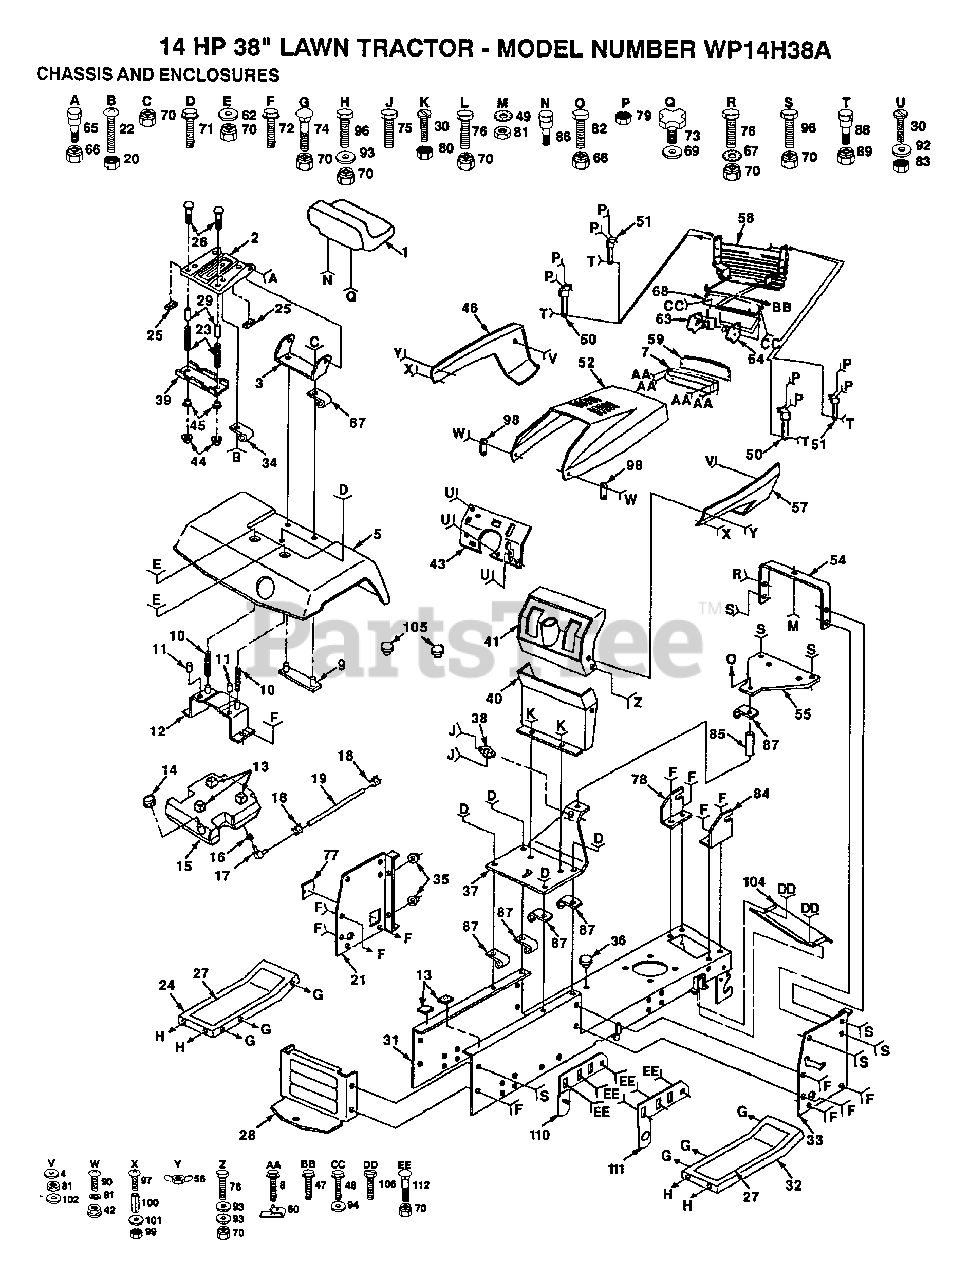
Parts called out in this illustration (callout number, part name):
4	WASHER PM
5	FENDER
10	SPRING COMPRESSIO
11	NUT-PUSH YT
13	PAD-SPACER LT
16	BUSHING OUTLET T
17	FUEL TANK STEM GT
18	HOSE CLAMP
20	"NUT,KEPS"
21	PANEL DASH LH
23	SPRING
25	STRIP FORM
27	FOOTREST PAD
28	DRAWBAR LT/YT
29	SPACER SPLIT
30	SCREW
33	DASH PANEL RH
39	BRKT SWITCH
40	LOWER DASH
42	WELDNUT
45	BUSHING
47	SCREW
48	SCREW
54	SUPPORT ASS'Y
57	"PANEL,SIDE RH "
59	LENS LT
60	"""J"" FASTENER LT"
62	WASHER
63	SUPPORT LH YTH
64	SUPPORT RH YTH
67	LOCKWASHER
69	WASHER
71	SCREW LT
72	SCREW
73	"KNOB 1/2"" YT"
74	BOLT
76	BOLT
77	COVER ACCESS
78	SUPPORT LH YTH
79	NUT
82	BOLT
84	SUPPORT RH YTH
85	SPACER
86	"BOLT,SHOULDER"
87	CLIP T
90	SCREW
91	LOCKWASHER
92	WASHER
93	WASHER
94	WASHER
97	SCREW
98	HOOD LATCH T
100	SPACER LT
101	WASHER
102	WASHER
104	HEAT SHIELD
105	CAP SPRING
106	SCREW
110	BRKT ASM PIVOT LH
111	BRKT ASM PIVOT RH
112	BOLT
